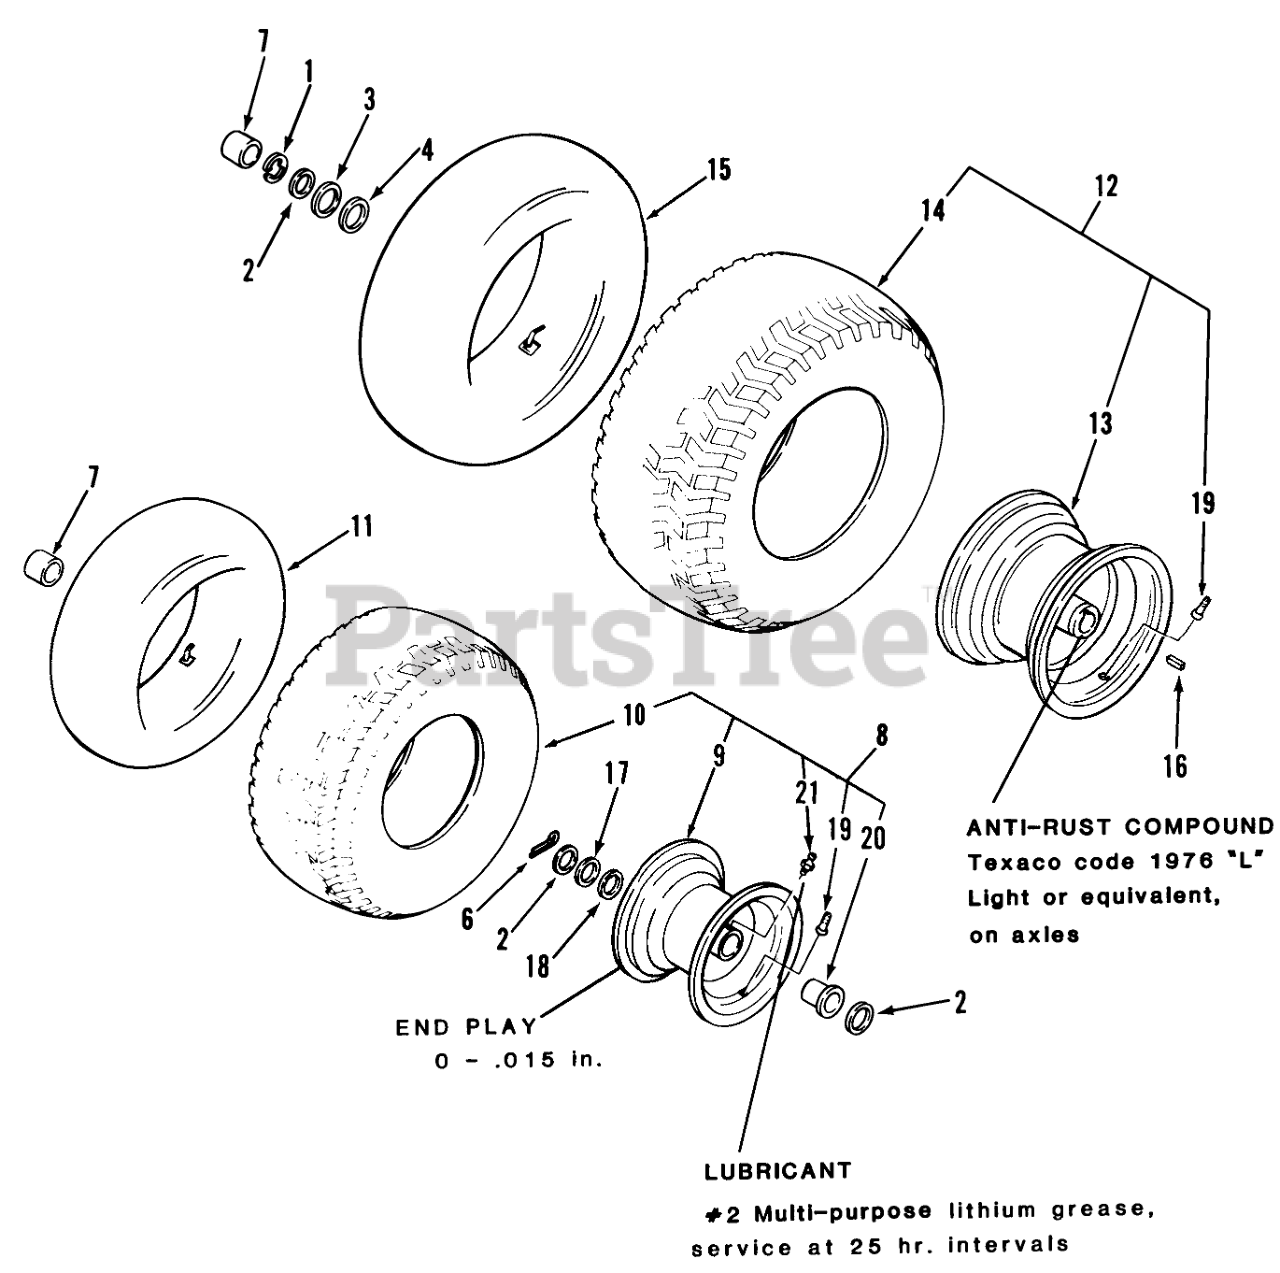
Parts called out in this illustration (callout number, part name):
1	E RING
1	E Ring
2	Washer
2	WASHER-FLAT
3	Washer
3	WASHER-SHIM
4	WASHER
6	COTTER PIN-4
7	HUB CAP-FLAT BLACK
7	HUB CAP
8	Wheel & Tire Assembly
9	ASSY-RIM
11	Tube (Service Only)
12	Assy-Wheel & Tire Rear
13	ASSY RIM
13	RIM ASSY
14	Rear Tire 20 x 10.0-10.0
16	Key
16	SQ KEY
17	WASHER
18	WASHER-SHIM
19	VALVE
20	FLANGE BEARING
21	Zerk
